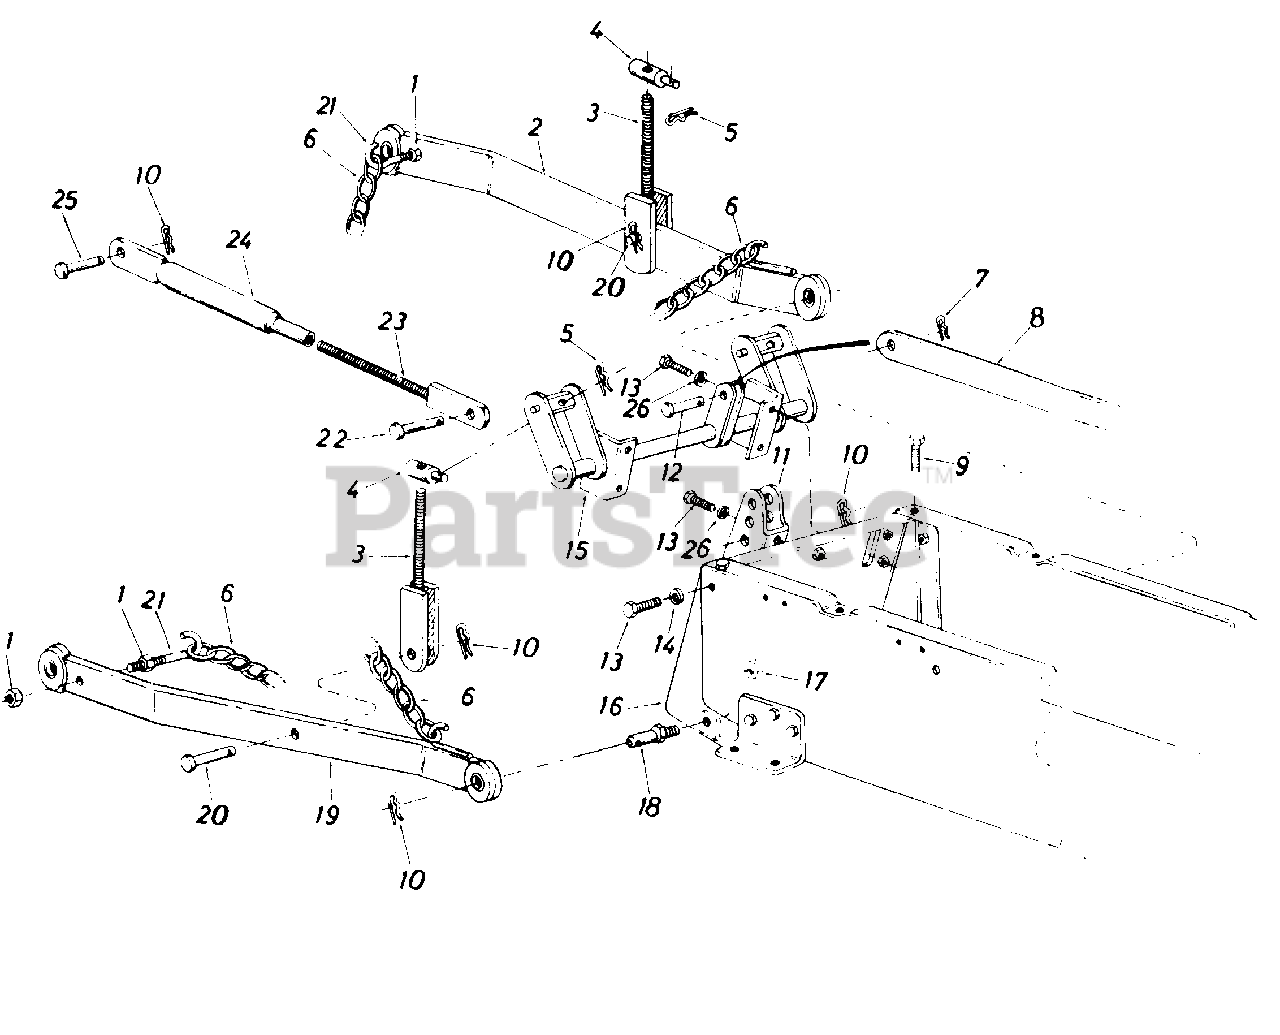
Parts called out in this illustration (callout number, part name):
1	Hex Cent. L-Nut 7/16-14 Thd.
2	Draft Bar Ass'y.-L.H.
3	Clevis Screw Ass'y.
4	Clevis Pin
5	Hitch Pin Clip
6	Chain 20 Links
7	Cotter Pin 1/8" Dia. x 1.25" Lg.
10	Hairpin Cotter
12	Clevis Pin
13	Hex Scr. 3/8-16 x .75" Lg.
14	L-Wash. 3/8" Scr. H.D.
18	Link Clevis Pin
19	Draft Bar Ass'y.-R.H.
20	Clevis Pin .63 Dia. x 1.66" Lg.
21	Hitch Chain Hook
22	Clevis Pin .63 Dia. x 2.4" Lg.
23	Clevis Screw
25	Clevis Pin .63 Dia. x 2.4" Lg.
26	L-Wash. 3/8" Scr. H.D.
13196-0648	PLATE-HITCH - TECH GRAY (0648)
13196-0665	PLATE-HITCH - YARDMAN GREEN (0665)
